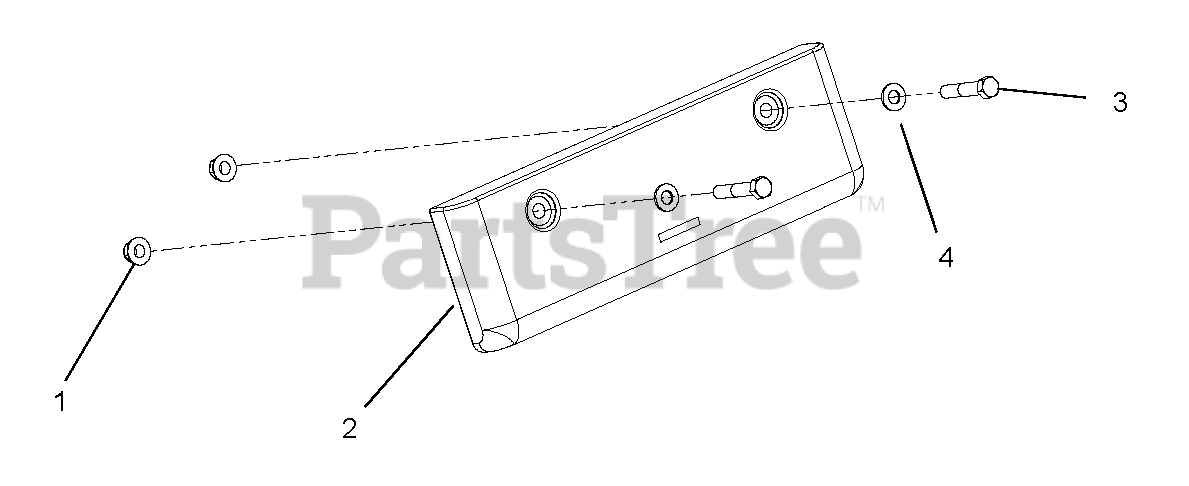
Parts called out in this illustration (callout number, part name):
1	Nut, Nyloc Flange .50-13
2	Weight, Cast Iron
3	Bolt, Hex .50-13 x 2.75
4	Washer, Flat Steel 531 x 1.06 x .095
